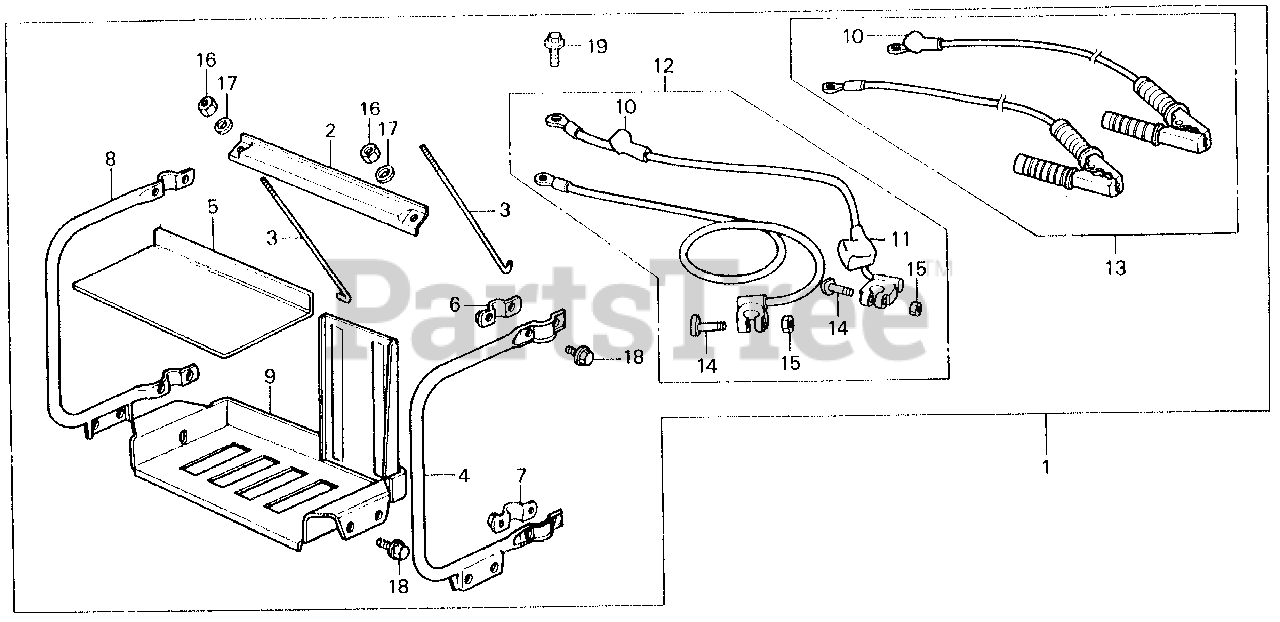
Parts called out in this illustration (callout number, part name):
1	TRAY KIT, BATTERY
2	PLATE, BATTERY SETTING
3	BOLT, BATTERY SETTING (220MM)
4	PIPE, FR. BATTERY GUARD
5	PLATE, BATTERY Use from Frame SN 1127014.
6	PLATE A, SETTING
7	PLATE B, SETTING
8	PIPE, RR. BATTERY GUARD
9	CASE, BATTERY
10	COVER, TERMINAL
11	COVER, BATTERY PLUS TERMINAL
12	CABLE ASSY., STARTING
13	WIRE, BATTERY
14	BOLT (6X32)
16	NUT, HEX. (6MM)
17	WASHER, PLAIN (6MM)
18	BOLT, FLANGE (6X12)
19	BOLT, FLANGE (8X16)
